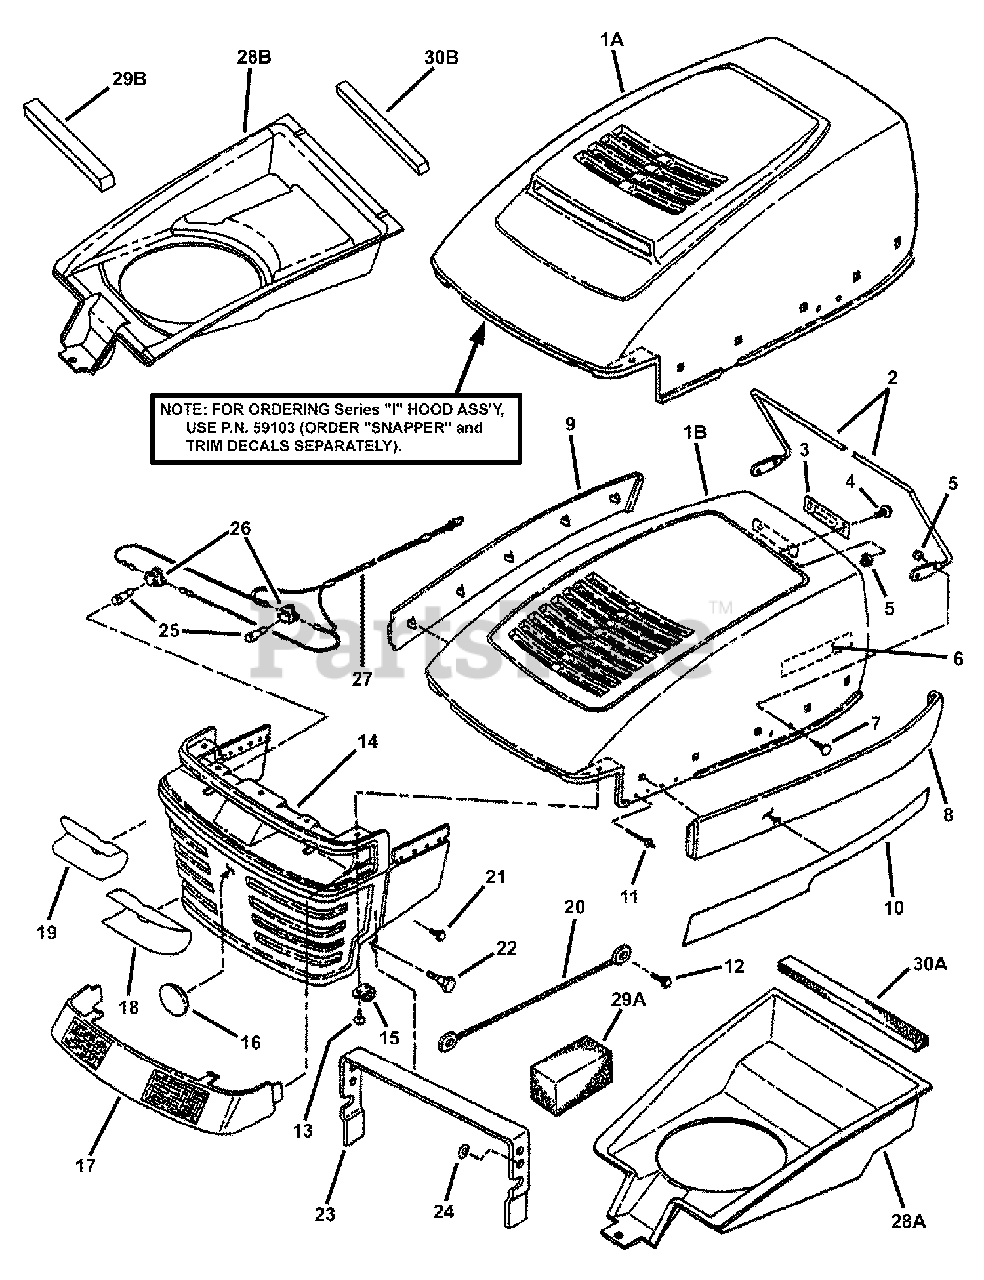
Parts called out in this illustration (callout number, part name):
1A	HOOD, Mozart-Scoop-Red
1B	HOOD, Mozart
2	ROD, Hood Support
3	CLIP, Spring-Latch
4	SCREW, 1/4-20 x 5/8 Pan Head Self-Tap (Torx)
5	NUT, 1/4-20 Hex Nyloc
6	DECAL, Snapper- Hood- 3D
7	BOLT, 1/4-20 x 5/8" Flat Head Square Neck, GR 2
8	PANEL, Hood, Left Hand, Black
9	PANEL, Hood, Right Hand, Black
10	DECAL, Hood (Right Hand)
10	DECAL, Hood (Left Hand)
10	DECAL, LX1642H RH- Mozart Hood
10	DECAL, LX1642H LH- Mozart Hood
11	POP RIVET, 1/8 x 3/8"
12	SCREW, 1/4-20 x 1-1/4" Hex Head Cap w/Locking Patch
13	SCREW, M4.8 x 1.59 x 16mm HXCRHD Sems Special
14	GRILL, Sloped, Black
15	CLIP, "J" Open Type .4 Bundle Dia., .281 Dia. Hole
16	DECAL, Molded Medallion
17	LENS, Rippled, Sloped
18	DECAL, Lens/Reflector-LH Sloped Grill
19	DECAL, Lens/Reflector-RH Sloped Grill
20	LANYARD, Hood, 14-3/4" long
20	LANYARD, Hood, 16-13/32" long
20	LANYARD, Hood 14-3/4" long
20	LANYARD, Hood, 16" long
21	SCREW, 5/16-18 x 1/2" Hex Washer Self-Tap
22	SHOULDER BOLT, 3/8-16 thread
23	BRACE. Hood Support/Stop
24	RETAINER, 5/16" Bolt
25	LAMP 1141
26	SOCKET, Headlight Snap-In
27	HARNESS, Headlight M&G Sockets
28A	PLENUM
28B	PLENUM
29A	FOAM, 2 x 2 x 3.5"
29B	FOAM, 1 x 1 x 10"
30A	FOAM, 1/2 x 3/4 x 14.25"
30B	FOAM, 3/4 x 3/4 x 10-3/4"
